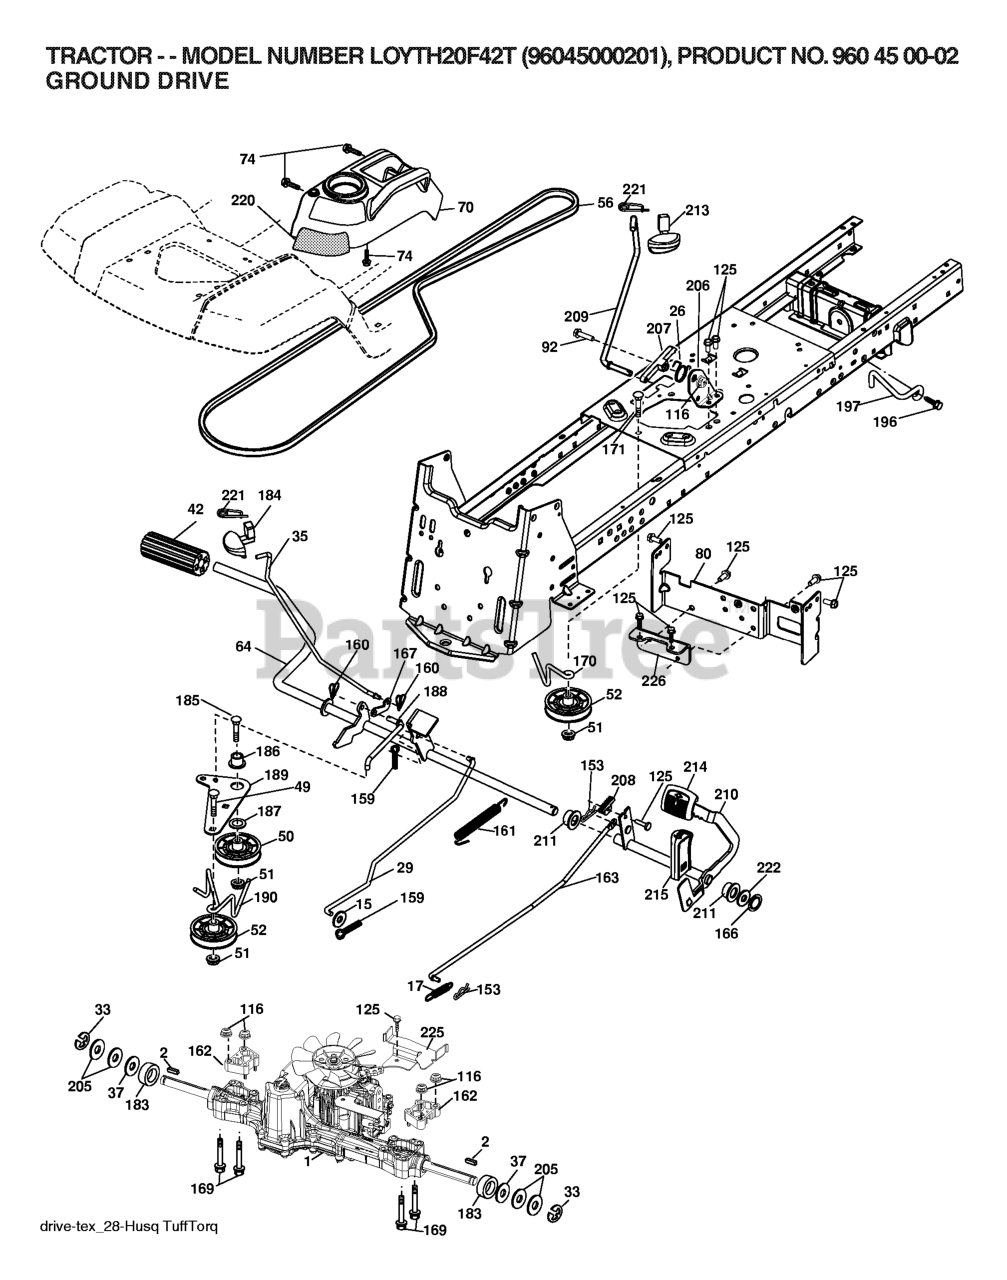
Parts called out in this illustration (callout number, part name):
2	SQUARE KEY
15	WASHER
17	SPRING.BRAKE.K46
26	SPRING.RETURN.CRUISE
29	ROD.BRAKE.K46
35	ROD.BRAKE.PARKING.GT.H
42	PEDAL COVER T
50	IDLER.FLAT.910.OFFSET
51	NUT LOCK FLG 3/8-16 UNC
52	IDLER.V-GROOVE.910.OFFSET
56	V-BELT.MOWER.92.40.42/K46
64	SHAFT.ASM.PEDAL.BRK.CNTR
70	RP CONSOLE.ASM.PCH.W/TB
74	SCREW.HI-LO.CONSOLE
80	STRAP.TORQUE.HG3000/K46
92	BOLT
116	NUT LOCK HEX FLANGE 5/16-18
125	SCREW
153	RETAINER M
159	COTTER PIN
160	RETAINER CLIP
161	SPRING.RETURN.CLUTCH.2006
162	SPACER.TRANSAXLE.18&22
163	ROD.CONTROL.PEDAL.K46
166	NUT.PUSH.625.2006
167	LATCH.BRAKE.SPRING
169	BOLT.HEX.FLNG.5/16-18X3.75
170	KEEPER.V-IDLER.CENTER.
183	SPACER AXLE
184	HANDLE.PARKG.BRK.HUSQ X667
186	SPACER.RETAINER
187	WASHER 12/32X2X10GA
188	RP.LINK.CLUTCH.GROUND.DRIVE
189	BELLCRANK.GROUND.DRIVE.TEX.
190	KEEPER.BELLCRANK.DRIVE
196	SCREW 3/8-16X1
197	LINK.CLUTCH.ANIT-ROTAT
206	BRKT.MOUNT.LATCH.CRUIS
207	LATCH.CONTROL.CRUISE
208	GEAR.SECTOR.CONTROL.CR
209	ROD.CONTROL.CRUISE.GT.
210	ROCKER.ASM.PEDAL.CONTR
211	BEARING.NYLON
213	KNOB.CONTROL.CRUSIE.HU
214	PEDAL.FORWARD.TEX.GT.4
215	PEDAL.REVERSE.TEX.GT.4
220	REFLECTOR.RH.TEX GT
221	RETAINER.SPRING.CLIP.H
222	WASHER
225	KEEPER.BELT.TRANSAXLE.K46
226	BRKT.MOUNT.TORQUE.K46.
